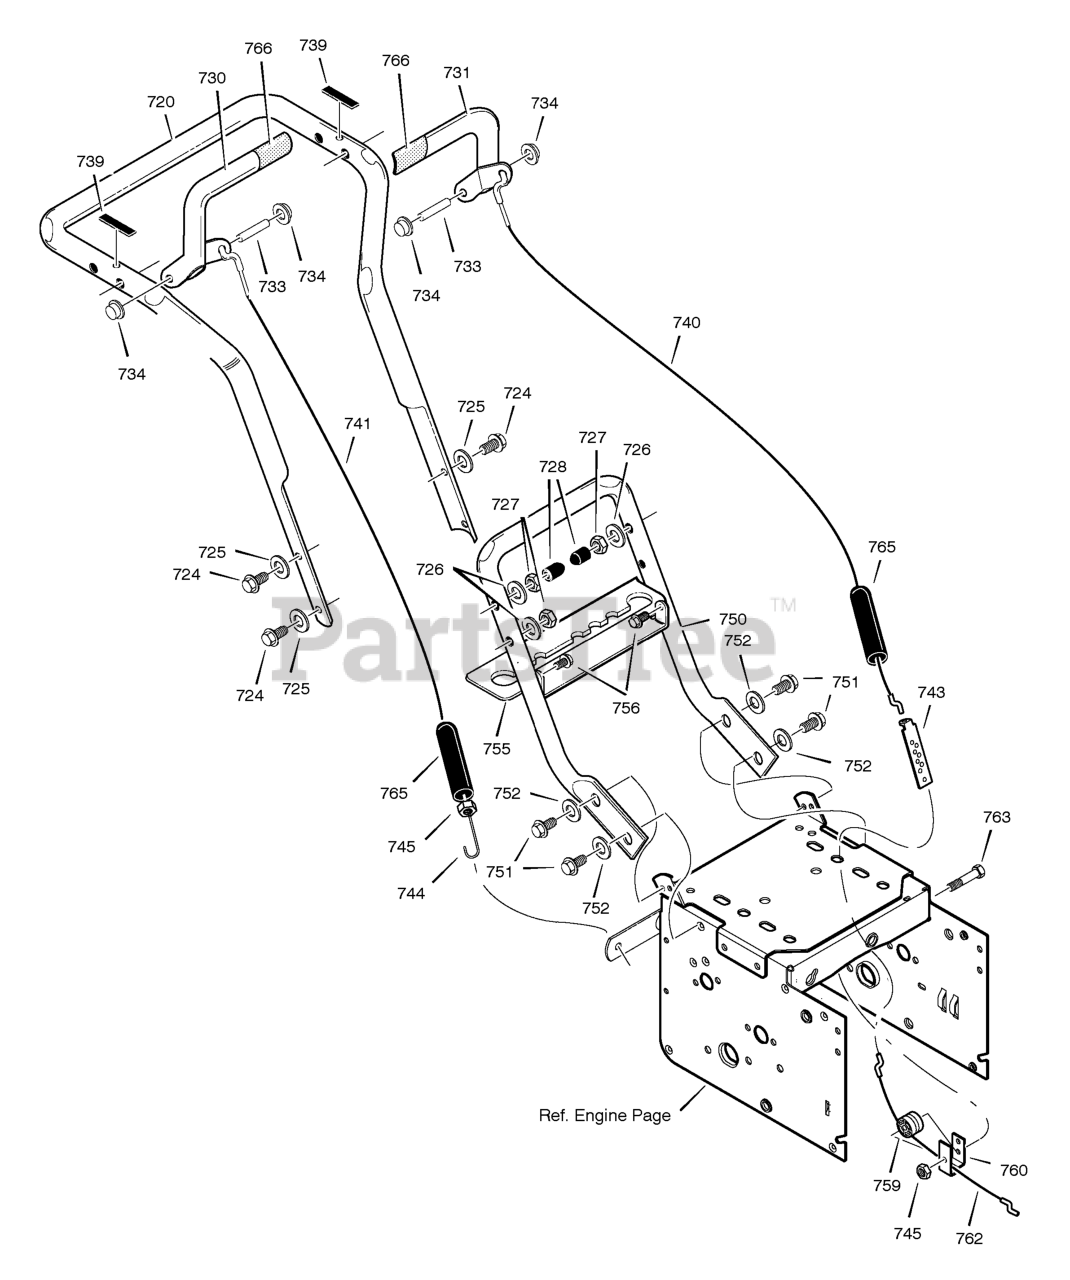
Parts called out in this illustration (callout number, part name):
720	HANDLE, UPPER
724	SCREW, 5/16-18 x 2.75
725	WASHER, FLAT
726	WASHER, SPTLK .31X.58X.08
727	NUT, 5/16-18 REGHEX
728	STOP, RED PLASTIC
730	CLUTCH HANDLE, RIGHT
731	CLUTCH HANDLE, LEFT
733	PIN, PIVOT CLUTCH
734	NUT, PUSH ON CAP
739	BUMPER, RECTANGLE
740	CABLE, CLUTCH 28.44L
741	CABLE, AUGER CLUTCH
743	BRACKET, CABLE ADJUSTER
744	SPRING, AUGER CLUTCH
745	NUT, 1/4-20
750	HANDLE, LOWER
751	SCREW, TAP 5/16-18 X .75
752	WASHER, SPTLK
755	BRKT, GEAR SELECTOR
756	SCREW, .25 X .75 X .51
759	SPOOL-CABLE, AUGRT CLUTCH
760	BRACKET, CABLE SPOOL YZ
762	CABLE, LOWER DRIVE 12"
763	BOLT, HEX 1/4-20 X 1.75 YZ
765	BOOT, CLUTCH SPRING
